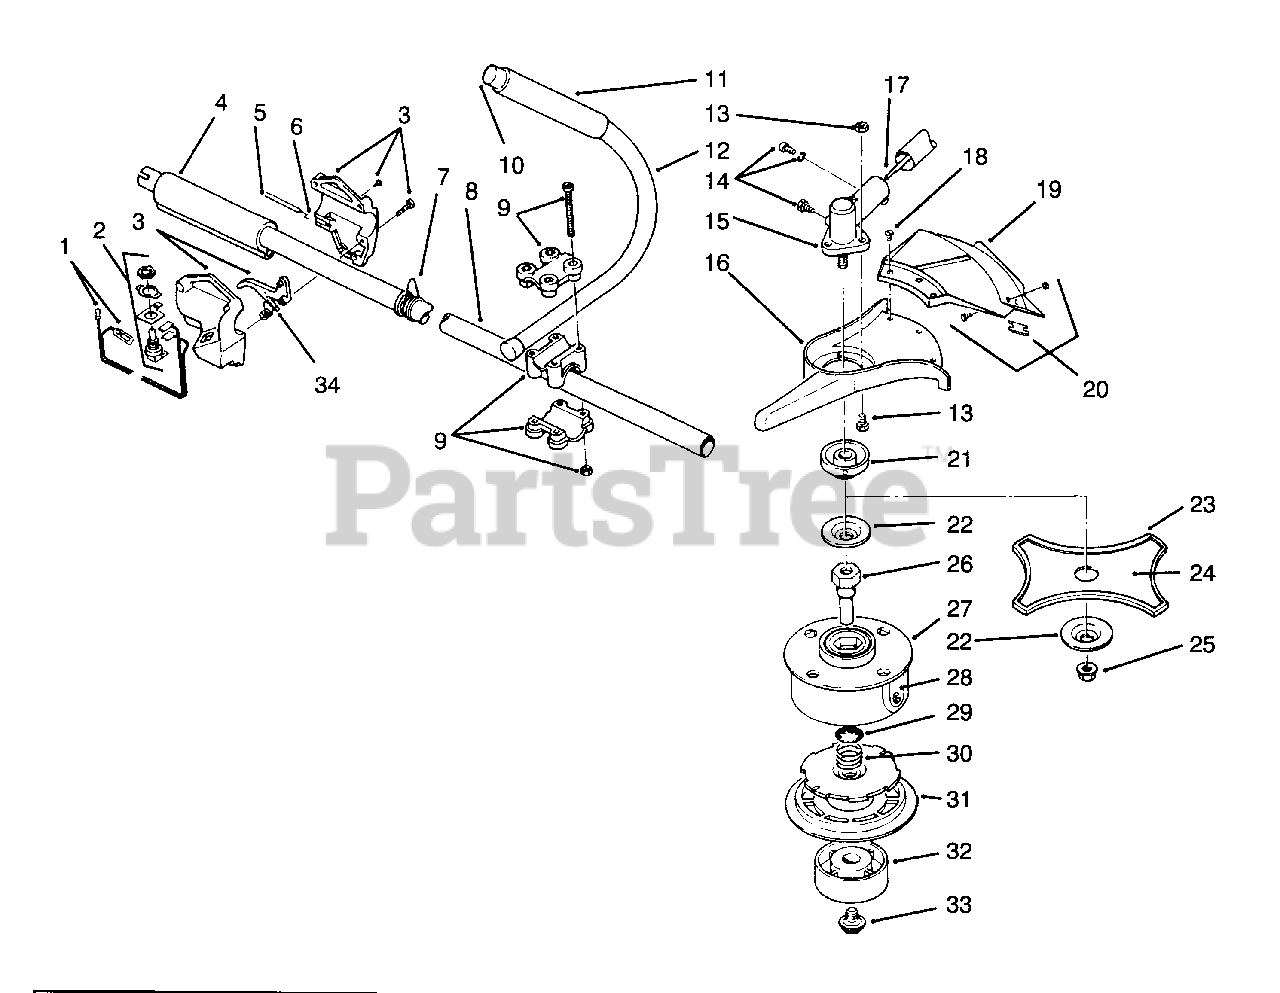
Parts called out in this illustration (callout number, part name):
1	Assembly-Wire Lead
2	Assembly-Switch
3	Assembly-Throttle Trigger
4	Grip-Handle, Main
5	Assy.-Throttle Cable
6	Cable-Throttle
7	Clamp-Shoulder Strap
8	Assy.-Drive Shaft
9	Assy.-Handle Bracket (Incl. 4 Screws 7 4 Nuts)
10	Closure-Tube
12	Assy.-J-Handle (Incl. Ref. No. 10 & 11)
13	Screws-Guard Mount
14	Screws & Grease Plug
15	Assembly-Gear Box
16	Mount-Guard
17	Shaft-Flexible Drive
18	Screws-Guard Mounting
19	Assy.-Guard & Blade (Incl. Ref. No. 20)
20	Assembly Blade (Incl. 2 Screws & 2 Nuts)
21	Driver-Blade
22	Washer-Lower Retaining
23	Cover-Blade
24	Blade (Incl. Ref. No. 23)
25	Nut-Lock
26	Shaft-Spool
27	Assy.-Outer Spool & Eyelet
29	Retainer (10 Pack)
31	Reel-Inner
32	Assy.-Bump Head
33	Assy.-Bump Head Knob
34	Spring-Throttle Trigger
